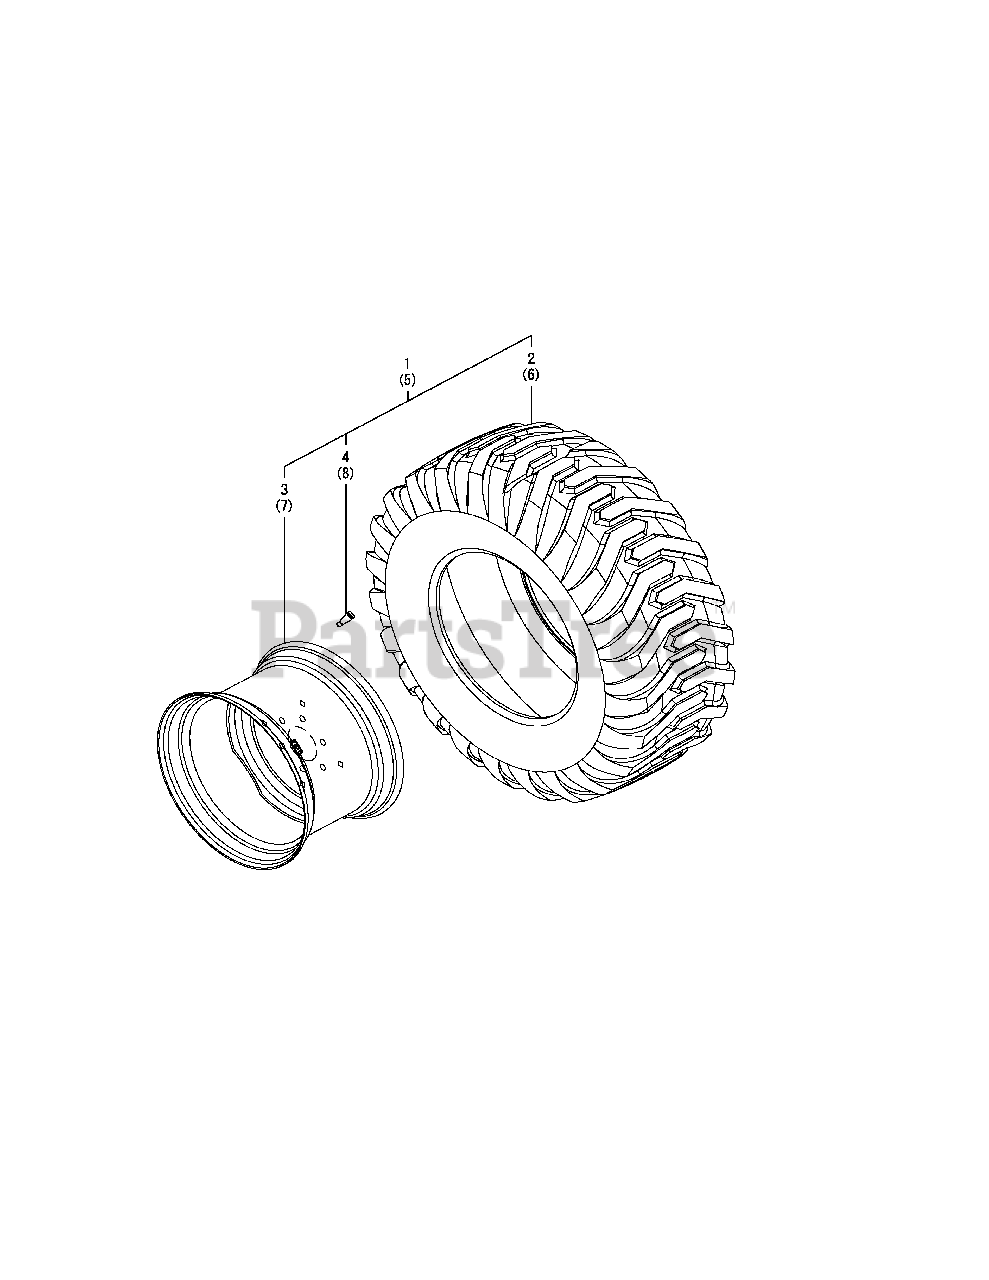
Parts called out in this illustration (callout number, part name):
1	TIRE ASM-REAR IND LH
2	TIRE-IND 15X19.5
5	TIRE ASM-REAR IND RH
6	TIRE-IND 15X19.5
